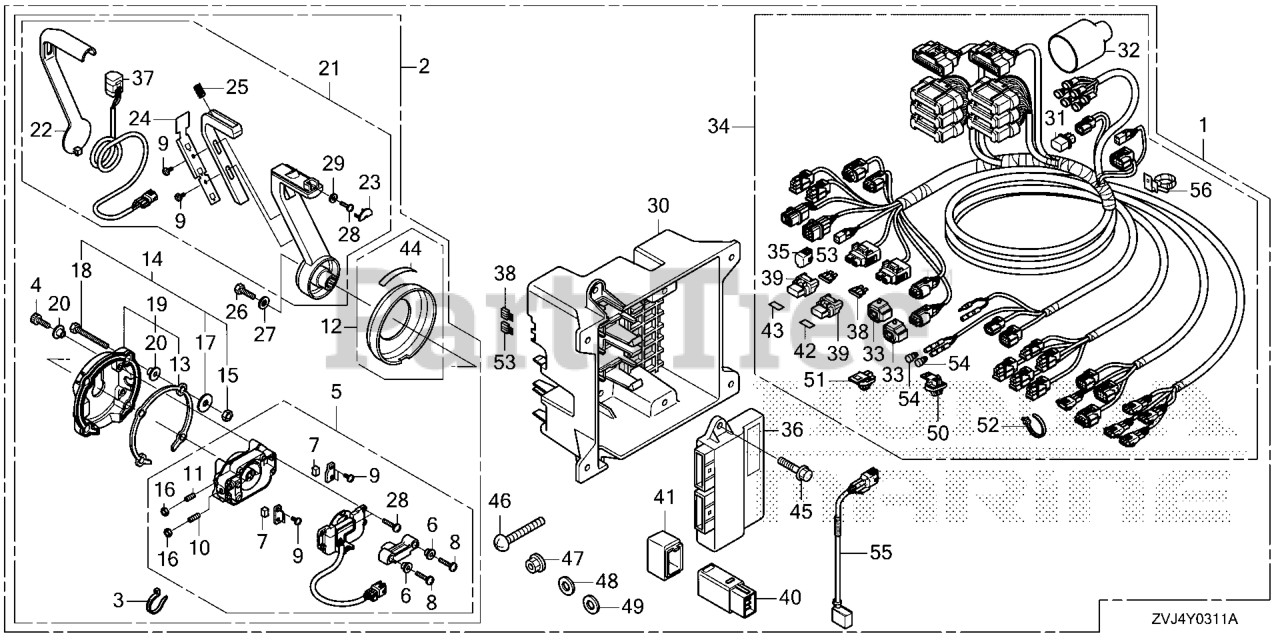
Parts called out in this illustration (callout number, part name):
1	BOX KIT, REMOTE CONTROL (FLUSH MOUNT)
1	BOX KIT, R/C
2	BOX ASSY., REMOTE CONTROL (FLUSH MOUNT)(RH)
3	BAND, NYLON
4	BOLT, SOCKET
5	HOUSING ASSY. (FLUSH MOUNT)
6	COLLAR, STOPPER
7	SHOE, BRAKE
8	SCREW
9	SCREW
10	SCREW SET
11	SCREW SET
12	COVER ASSY. (FLUSH MOUNT)
13	SHEET, WATERPROOF (FLUSH MOUNT)
14	NUT SET, MOUNTING
15	NUT, NYLON
16	NUT
17	WASHER
18	BOLT
19	BASE ASSY. (FLUSH MOUNT)
20	COLLAR, BASE
21	LEVER ASSY. (FLUSH MOUNT)
22	PANEL, LEVER (FLUSH MOUNT)
23	CAP, LEVER (FLUSH MOUNT)
24	PLATE, LEVER PANEL
25	SPRING, COIL
26	BOLT
27	WASHER
28	SCREW
29	WASHER
30	CASE, CONTROL UNIT
31	TERMINATOR ASSY.
32	COVER, CONNECTOR (NOT AVAILABLE)
33	SUSPENSION, CONNECTOR
34	CABLE ASSY., REMOTE CONTROL (MAIN)
34	CABLE, REMOTE CONTL
35	CAP, DUMMY (WPC 4P 090 M) (RED)
36	UNIT ASSY., CONTL
37	SWITCH ASSY., POWER TRIM-TILT (FLUSH MOUNT)
38	FUSE, BLADE (3A)
39	COVER ASSY., FUSE
40	RELAY ASSY., MAIN
41	SUSPENSION, RELAY
42	LABEL, FUSE (3A)
43	LABEL, FUSE (5A)
44	MARK, FLUSH MOUNT
45	BOLT, FLANGE (6X20)
46	SCREW, PAN (5X40) DUAL QTY = (8) (SINGLE)
47	NUT, FLANGE (5MM)
48	WASHER, PLAIN (5MM)
49	WASHER, SPRING (5MM)
49	WASHER, SPG (5MM)
50	CLIP, CONNECTOR (DARK BLUE)
51	CLIP, CONNECTOR (DARK BROWN)
52	CLIP, HARNESS BAND (145MM) (BLACK)
53	FUSE, MINI (5A)
54	PLUG, CONNECTOR (INNER) (TROLLING CONTROL)
55	RELAY ASSY., CONTROL (NOT AVAILABLE)
56	HOLDER, CONNECTOR (128.6MM) (NATURAL)
